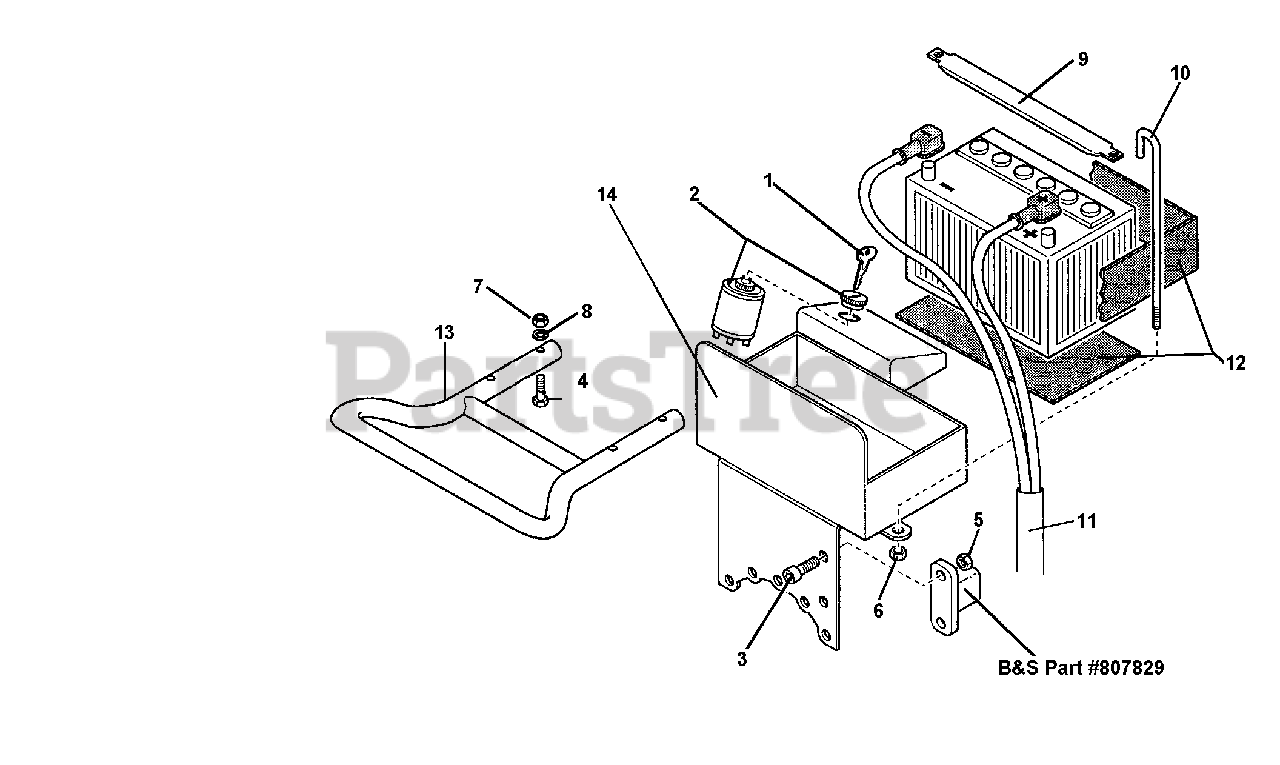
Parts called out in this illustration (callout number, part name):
3	SCREW TE M6X10
4	SCREW M8X60
6	NUT, SELF LOCKING M6
7	NUT, SELF LOCKING M8
8	FLAT WASHER 8.4
9	BATTERY BRACKET
10	BATTERY TIEROD
11	ELECTRIC START CABLES 5HP & 7HP B&S
12	BATTERY PADS
13	BUMPER 5HP B&S
14	BATTERY SUPPORT, 5HP & 7HP B&S
